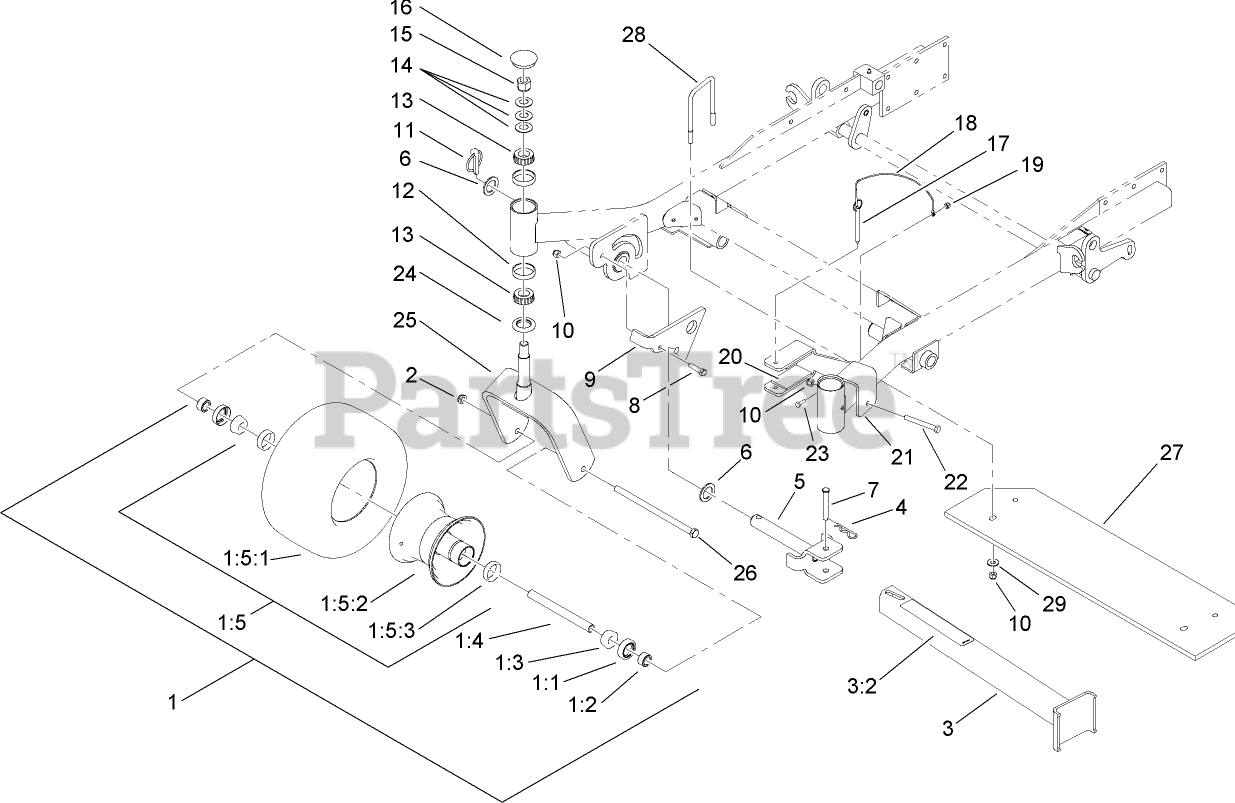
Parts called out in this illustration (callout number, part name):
1	CASTER WHEEL ASM
1:1	SEAL-BEARING
1:2	SPACER-BEARING
1:3	BEARING-CONE, TAPER
1:4	SPACER-CASTER, FRONT
1:5	WHEEL AND TIRE ASM
1:5:3	BEARING-CUP
2	NUT-LOCK, NI
3	Leg ASM
3:2	DECAL-Z STAND
4	PIN-HAIR
5	PIN-PIVOT
6	WASHER-THRUST
7	PIN-CLEVIS
8	SCREW-HH
9	BRACKET-LATCH
10	NUT-LOCK, NI
11	PIN-LYNCH
12	BEARING-CUP, TAPERED
13	BEARING-CONE, TAPERED
14	WASHER-BELLVILLE
15	NUT-LOCK, NI
16	CAP-GREASE
17	PIN-HITCH, COTTERLESS
18	LANYARD-NYLON
19	NUT-LOCK, NI
20	Cushion-Rubber
21	BRACKET-CRADLE
22	SCREW-HH
23	SCREW-HH
24	SEAL-GREASE
25	CASTER-FORK
26	Screw-HH
27	BAR-WEIGHT
28	U-BOLT, 3IN
29	WASHER-FLAT
